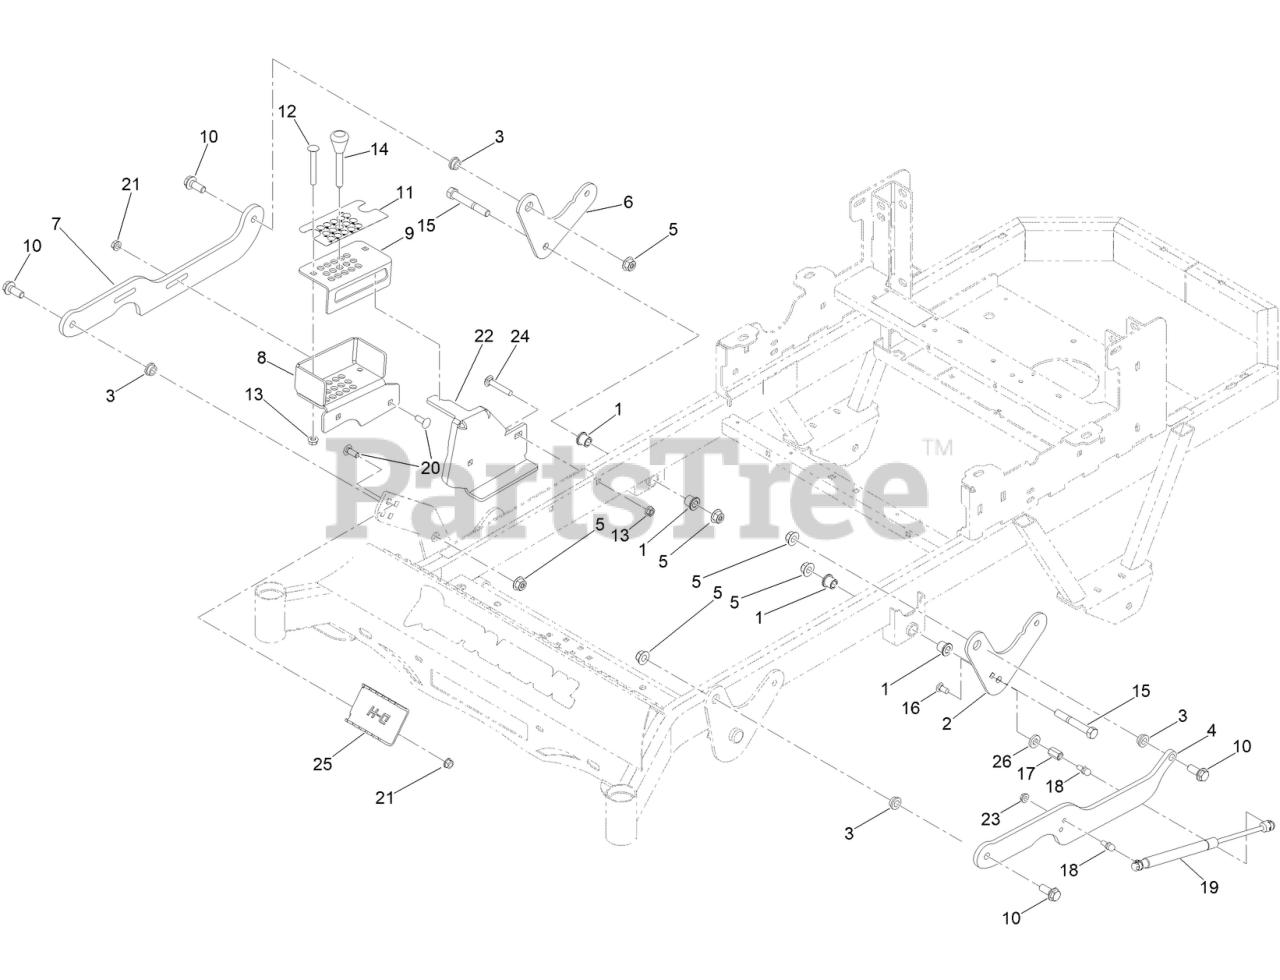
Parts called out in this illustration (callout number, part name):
1	BUSHING-FLANGE
2	ARM-DECKLIFT REAR (1/4")
3	1/2IN ID X 3/4IN OD X 3/8IN FLANGE BUSH
4	LINK-DECKLIFT
5	1/2-13 HEX FLANGE 2-WAY REV CNTR L/NYZ
6	ARM-DECKLIFT REAR (1/4")
7	2024 DECK HEIGHT ARM RT LINK
8	BRACKET PIN SYSTEM (BOTTOM) PAINTED GREY
9	2022 DHI PIN ARM LINK TOP BRKT
10	1/2-13X1.25IN HEX FLANGE BOLT (GR.8) YZ
11	DECAL-HEIGHT OF CUT
12	(3/8-16 X 3 CARRIAGE BOLT (GR.5) ZC/YEL)
14	MAGNETIC PIN FOR STAND ON MWR
15	1/2-13 X 3-1/2 HEX C/S GR 5 ZINC YELLOW
16	3/8 X 3/4IN GR 8 CARR BOLT ZINC
17	HEX COUPLING NUT - REDUCER (3/8" TO 5/16
18	5/16-18X1.286 DAMPER BALL STUD (.562 TL)
19	RZ DECK ASSIST GAS SPRING
20	SCREW-CARR
21	NUT-HHF, WHIZ
22	2022 DECK LOCK PIN TUBE BRKT
23	NUT-HF
24	SCREW-CARR
25	MWR DECK HEIGHT FOOT PEDAL PAINT
26	5/16IN USS FLAT WASHER (3/8 ID X 7/8 OD)
